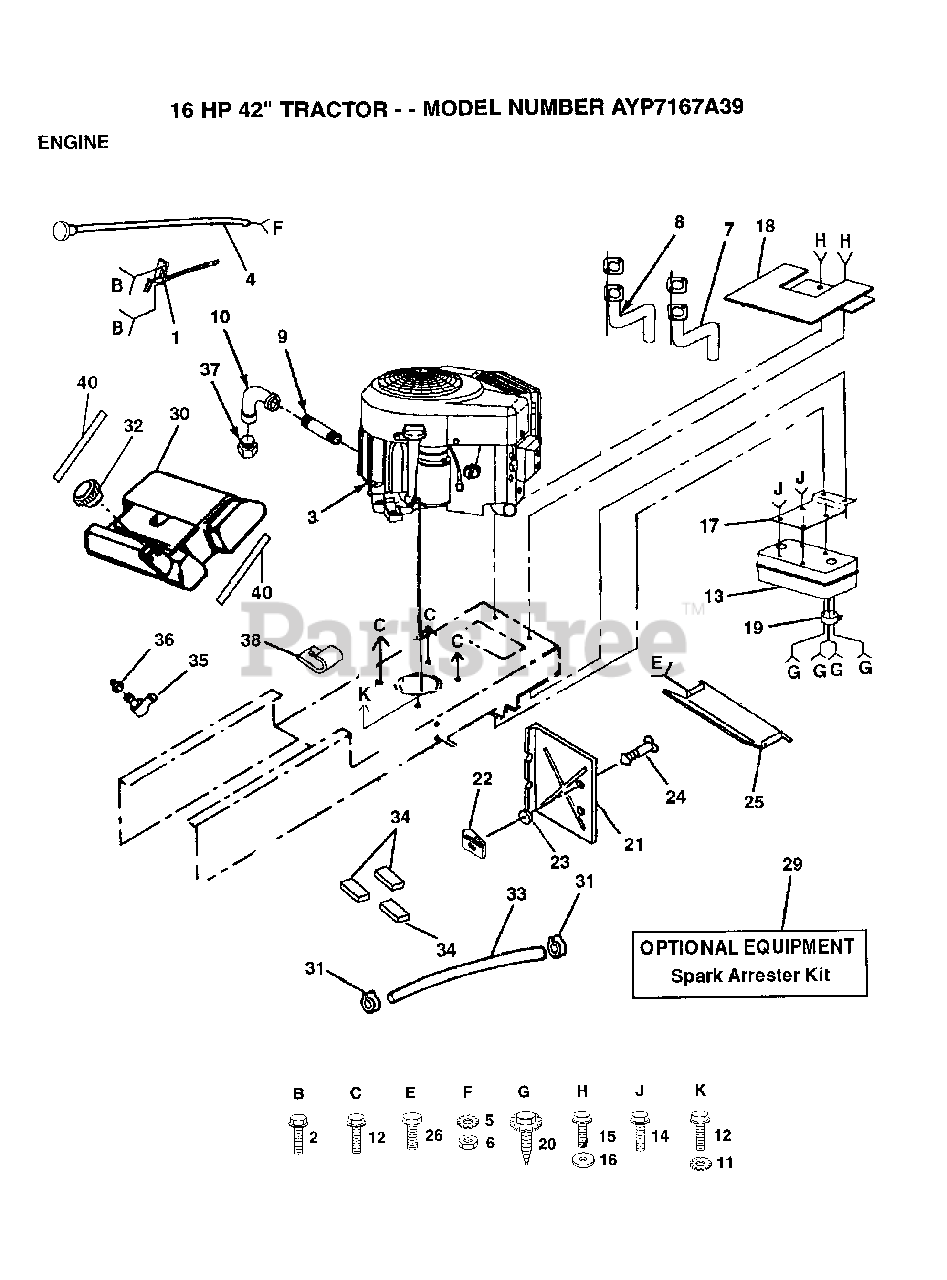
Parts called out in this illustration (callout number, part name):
2	SCREW LT
4	CHOKE CONTROL
5	LOCKWASHER
7	TUBE ASSY EXH RH
8	TUBE ASSY EXH LH
9	PIPE NIPPLE LT
10	ELBOW
11	LOCKWASHER
12	SCREW LT
14	SCREW ST
15	SCREW
16	WASHER
17	BRACKET MUFFLER
19	DEFLECTOR.222573
21	HEAT SHIELD
22	RECEPTACLE LT
23	RETAINER LT
24	STUD.1/4.TURN
25	HEAT SHIELD
26	SCREW
31	HOSE CLAMP
33	FUEL LINE T
34	PAD-SPACER LT
35	BUSHING OUTLET T
36	STEM.TANK.FUEL
38	CLIP T
40	PAD IDLER TI
